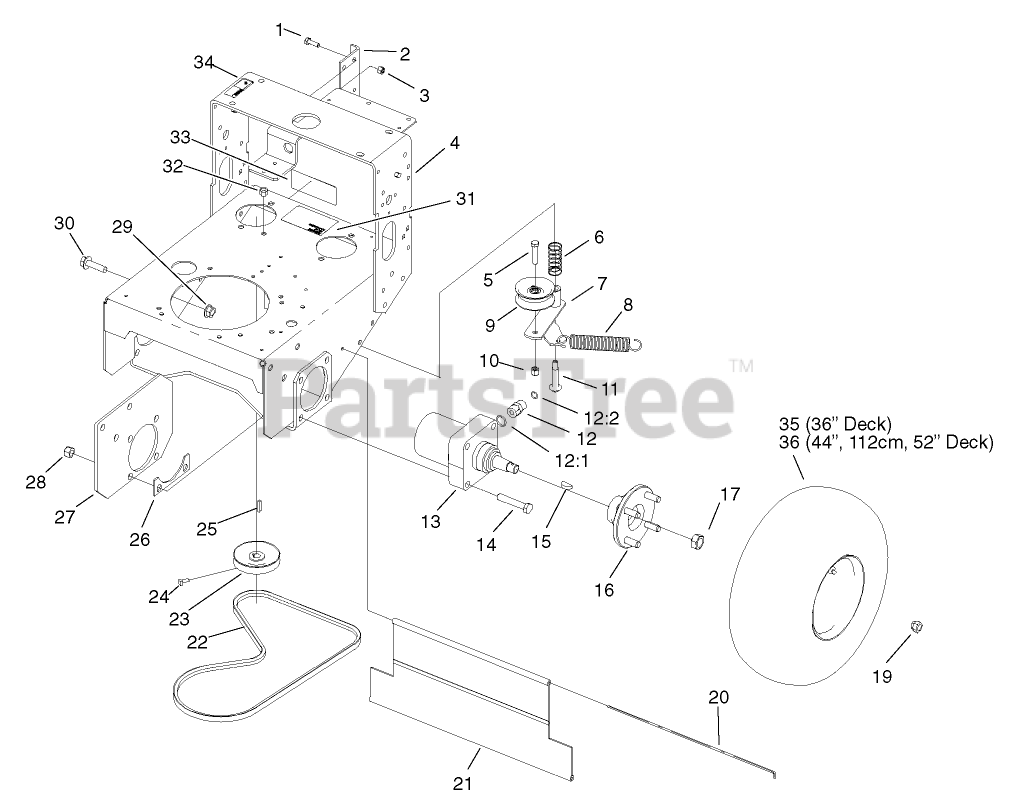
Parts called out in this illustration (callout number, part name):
1	SCREW-HH
2	BRACKET-BUSHING
3	NUT-LOCK, NI
4	FRAME ASM
5	SCREW-HH
6	SPRING-COMPRESSION
7	IDLER LEVER ASM
8	SPRING
9	PULLEY
10	NUT-LOCK, NI
11	BOLT-WHEEL
12	FITTING-STRAIGHT
12:1	O-RING
12:2	O-RING
13	HYD MOTOR ASM
14	SCREW-HH
15	KEY-PUMP
16	WHEEL HUB ASM
17	NUT-MOTOR, WHEEL
19	NUT-LUG
20	ROD-SHIELD
21	SHIELD-TRAILING
22	BELT-V
23	PULLEY-PUMP
24	SCREW-SET
25	KEY-WOODRUFF
26	SPACER-FRAME
27	PLATE-FRAME
28	NUT-LOCK, NI
29	NUT-HF
30	SCREW-HHF
31	DECAL-ADJUSTMENT, VALVE
32	NUT-LOCK
33	DECAL-CAUTION
34	DECAL-SHUT OFF, FUEL
35	WHEEL AND TIRE ASM
36	WHEEL AND TIRE ASM
36:3	STEM-VALVE
